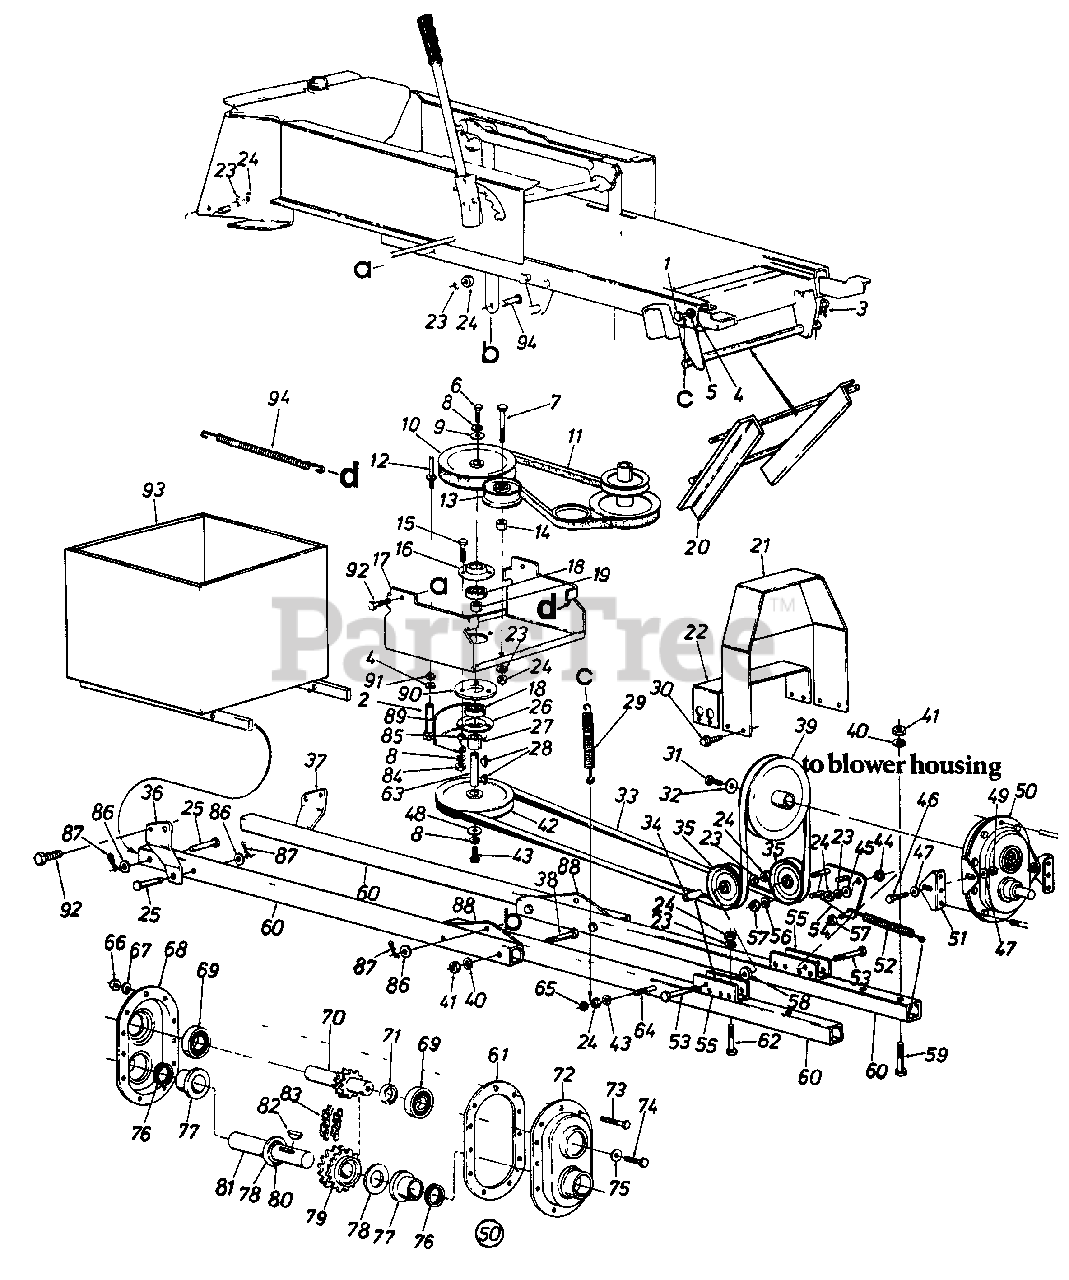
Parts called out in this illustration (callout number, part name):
1	Hex Bolt 1/4-28 x 1.50"
2	Clevis Pin Special 3/8" Dia. x 2.62" Lg.
3	Inter. Cotter Pin 1/2" Dia.
4	L.-Wash. 1/4" I.D.
5	Hex Nut 1/4-28 Thd.
6	Hex Bolt 3/8-24 x 1.0" Lg.
7	Hex Bolt 3/8-16 x 2.25" Lg.*
8	L.-Wash. 3/8" I.D.*
9	L.-Wash. .39" I.D. x 1.25" O.D.
10	5/8 ' "V-Pulley .790" I.D. x 6.50 O.D.
11	"V" Belt 1/2" x 52.0" Lg.
12	Belt Guard Pin 1/4" Dia, xl.68" Lg.
13	Fl.-ldlerw/ flanges3.75" O.D.
14	Spacer .385" I.D. x .630" O.D. x .760" Lg.
15	Hex Bolt 5/16-24 x 1.50" Lg.
16	Open Brg. Housing 1.85" I.D.
19	Spacer 1.0" O.D. x .790" I.D. x .350" Lg.
20	Guide Bracket Ass'y.
21	Belt Cover Ass'y.
22	Belt Cover Brkt.
23	L.-Wash. 3/8" I.D.*
24	Hex Nut 3/8-16 Thd.*
25	Clevis Pin .50" Dia. x 2.75" Lg.
26	Bearing Housing 1.85" I.D.
27	Spacer .80" I.D. x 1.00" O.D. x .125" Lg.
28	Hi-Pro-Key 3/16 x 5/8"
29	Extension Spring 1.00" O.D. x 6.44" Lg.
30	Hex Wash. HD. Sf. Tap Scr. 5/16-24x .50" Lg.
31	Hex L.-Bolt 3/8-24 x 1.00" Lg.
32	Bell.-Wash. .400"I.D. x1.25" O.D.
33	"V"-Belt 1/2" Ax 112.0" Lg.
34	Spacer .39" I.D. x .62" O.D. x 1.74" Lg.
35	5/8" "V"-Belt Idler 4.00" O.D.
39	5/8" "V"-Pulley 1.00" I.D. x 7.50" O.D.
40	L.-Wash. 1/2" I.D.*
41	Hex Nut 1/2-13 Thd.*
42	5/8" "V"-Pullev .79" I.D. x 6.5"
43	Hex Bolt 3/8-24 x 1.0" Lg.
44	Shoulder Spacer .625" I.D.
45	Fl.-Wash. .400" I.D. x 1.25" O.D.
46	Hex Bolt 5/16-18 x .75" Lg.*
47	Bell.-Wash. .345" I.D. x .88" O.D.
48	Fl.-Wash. .39" I.D. x 1.25" O.D.
49	Hex Nut 5/16-18 Thd.*
50	Comp. Chain Gear Box Ass'y.
51	Gear Box Support Brkt.
52	Extension Spring .87" Dia. x 6.00" Lg.
53	Hex Bolt 3/8-16 x 3.0" Lg. (Grade 8)
56	Fl.-Wash. .385"I.D. x .87 O.D.
57	Hex Ins. L.-Nut 3/8-24 Thd.
58	Fl.-Wash. .400" I.D. x 1.25" O.D. x .157 Thk.
59	Hex Bolt 1/2-13 x 3.00" Lg.*
62	Hex Bolt 3/8-15 x 3.0" Lg. (Grade 8)
63	Shaft-.787" Dia. x 3.81" Lg.
64	Hex BoIt 3/8-16 x 3.25" Lg.*
65	Hex Cent. L.-Jam Nut 3/8-16 Thd.
66	Hex Nut 1/4-28 Thd.
67	Spr.-Wash. .270" I.D. x .57" O.D.
68	Gear Hsg. Half-L.H.
69	Ball Brq. 1.00"I.D. x2.00" O.D.
70	11-2 x .5 Pitch-Sprkit ShaftAss'y.
71	Spacer 1.00" I.D. x 1.18" O.D. x .440 Lg.
72	Gear Hsg. Half-R.H.
73	Hex Bolt 1/4-28 x 1.00" Lg. (Grade 5)
74	Hex L.-Bolt 3/8-24 x 1.00" Lg.
75	Bell.-Wash. .400" I.D. x 1.25" O.D.
76	Oil Seal 1.25" x 1.75" O.D.
77	Flange Brg. 1.252" I.D.
78	Fl.-Wash. 1.25" I.D. x2.00" O.D.
79	DBL Sprkt. 19-2 Teeth x .500" Pitch
80	Snap Ring for 1.25" Dia. Shaft
81	Gear Shaft 1.25" Dia. x 6.0" Lg.
82	#A Hi-Pro Key 1/4 x 7/8" Dia.
83	40-2 Chain 1/2" Pitch x 25 Links
84	Hex Nut 5/16-24 Thd.*
85	Spacer .380" I.D. x .625" O.D. x .227" Lg.
86	Fl.-Wash. .510" I.D. x 1.0" O.D.
87	Inter. Cot.-Pin 1/2" Dia.
91	Hex Nut 1/4-20 Thd.
92	Hex Bolt 3/8-16 x 1.0" Lg.-Gr. 5
93	Weight Box Ass'y.
94	Lift Brkt. Pin
